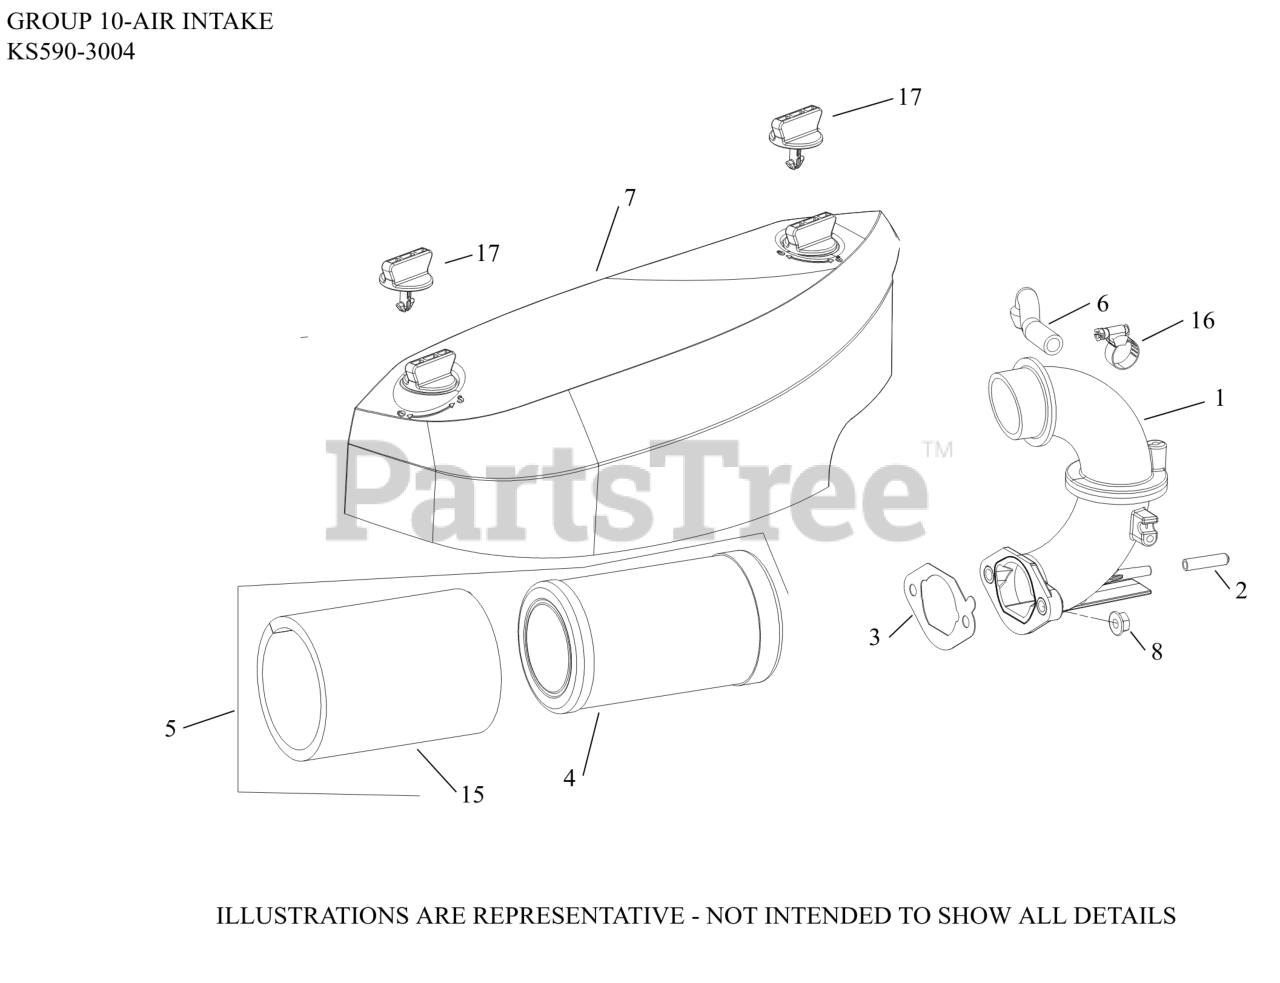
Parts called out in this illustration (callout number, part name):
1	ADAPTER, AIR CLEANER ASSY
2	CAP, MASKING
3	GASKET, CARBURETOR
4	ELEMENT, AIR FILTER
5	AIR FILTER KIT (STD)
6	HOSE, BREATHER
7	COVER, AIR CLEANER ASSY
8	NUT, FLG M6X1.0
15	ELEMENT, PRE-CLEANER
16	CLAMP, HOSE (KM)-USE 25 237 31-S
17	KNOB, AIR CLEANER COVER
